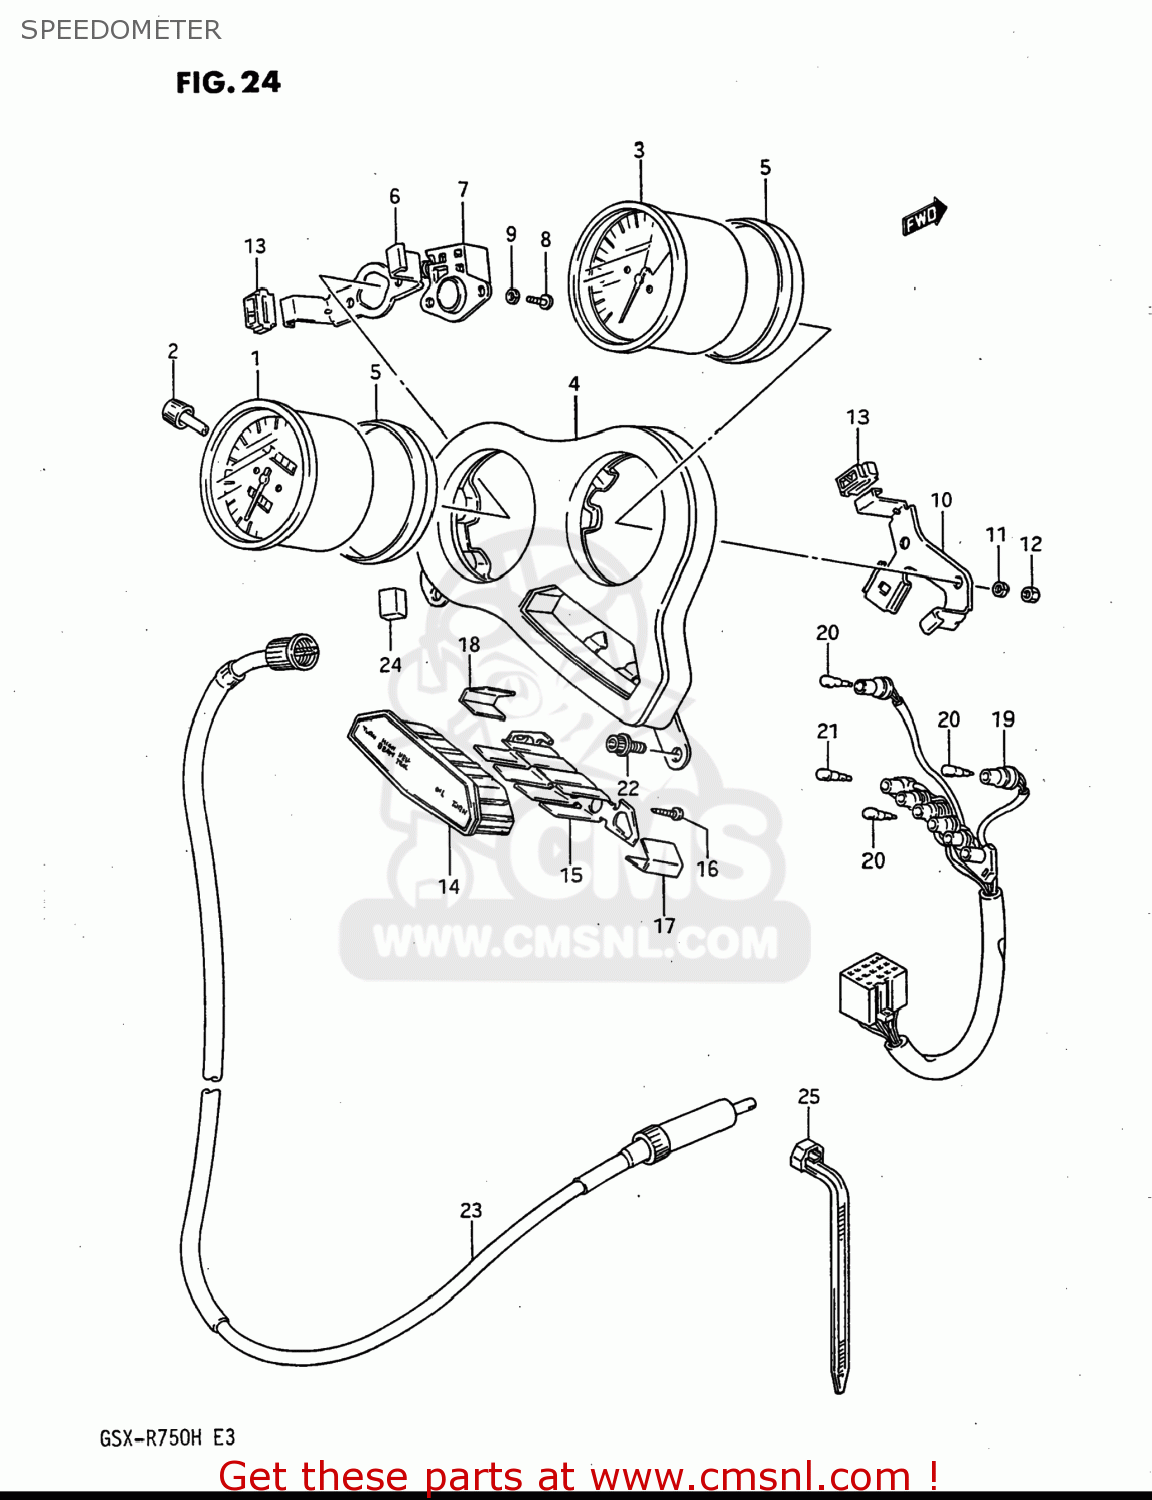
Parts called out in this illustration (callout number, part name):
1	SPEEDOMETER (MILE/KILO)
2	KNOB,TRIP
3	TACHOMETER
4	BRACKET,METER
5	CUSHION,METER
6	PLATE,SPEEDOMETER
7	BOX,METER GEAR
8	SCREW
9	LOCK WASHER
10	PLATE,TACHOMETER
11	WASHER
12	NUT
13	CUSHION
14	CASE,PILOT LAMP
15	PLATE,PILOT LAMP
16	SCREW
17	PLATE,TURN,R
18	PLATE,TURN,L
19	SOCKET
20	BULB(12V3W,WB371,T7)
21	BULB(12V1.7W,WB372,T7)
22	BOLT
23	CABLE ASSEMBLY,SPEEDOMETER
24	CUSHION,METER
25	CLAMP(L:95)
